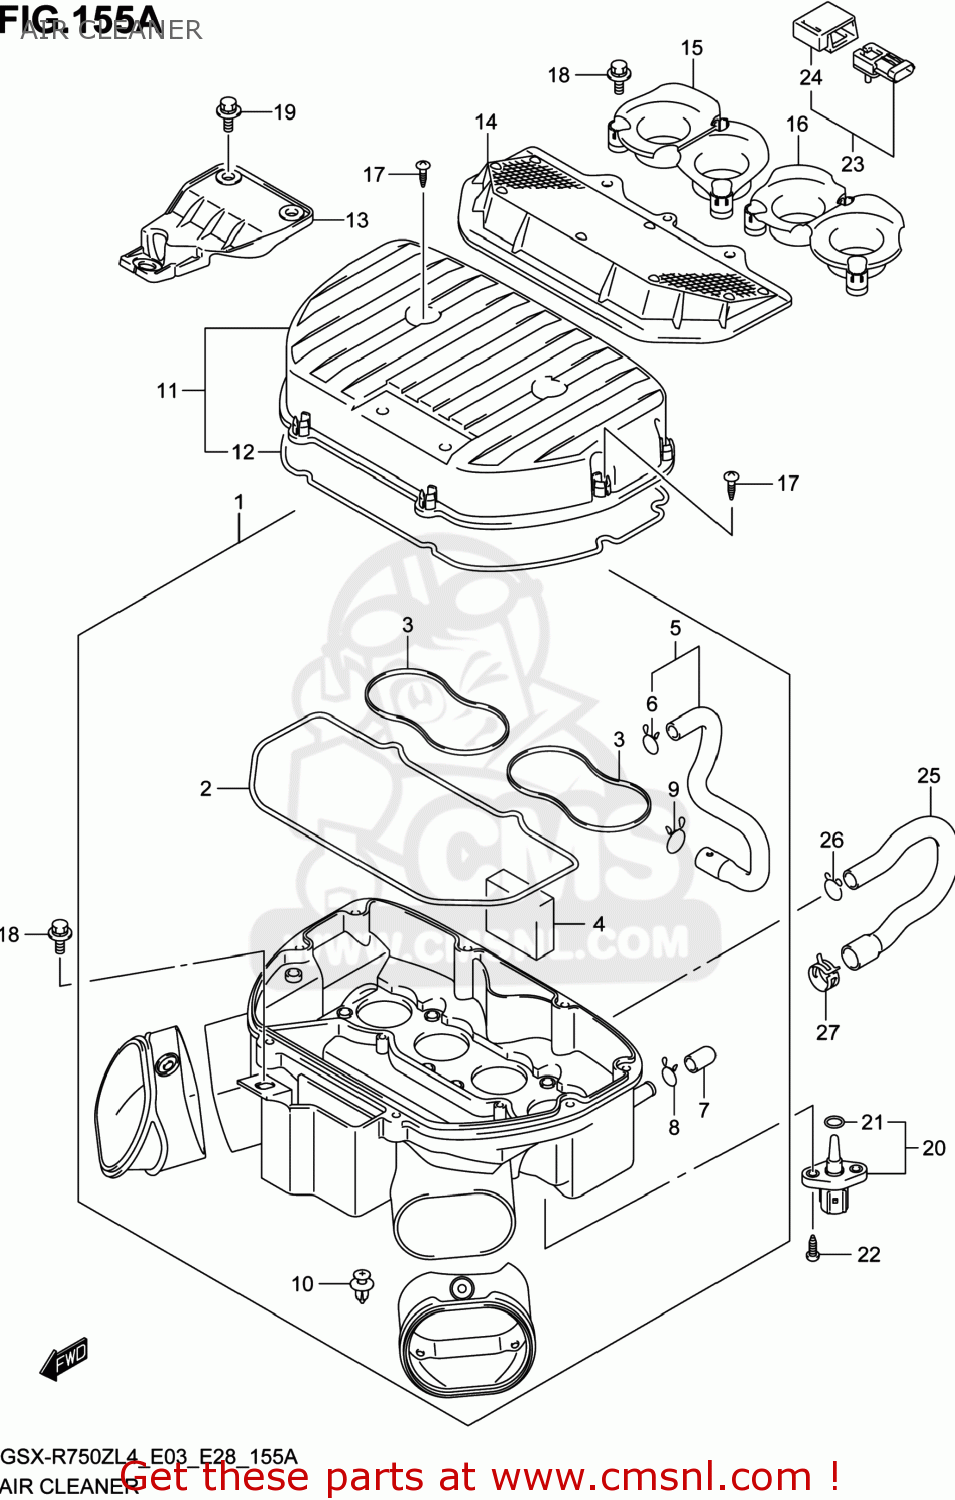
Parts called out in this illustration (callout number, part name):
1	CASE,AIR CLEANER
2	GASKET,CASE (NAS)
3	GASKET,CASE (NAS)
4	FILTER,BREATHER
5	TUBE,BREATHER
6	CLIP
7	PLUG
8	CLIP
9	CLIP
10	CLIP(BLACK)
11	CAP,AIR CLEANER
12	GASKET,CAP (NAS)
13	HOLDER,AIR CLEANER
14	FILTER ASSY
15	FUNNEL,OUTLET,R
16	FUNNEL,OUTLET,L
17	SCREW
18	BOLT,AIR CLEANER CASE
19	BOLT(6X16)
20	SENSOR,AIR TEMP
21	O RING
22	SCREW
23	SENSOR,AIR PRESSURE
24	COVER
25	HOSE
26	CLIP
27	CLIP
